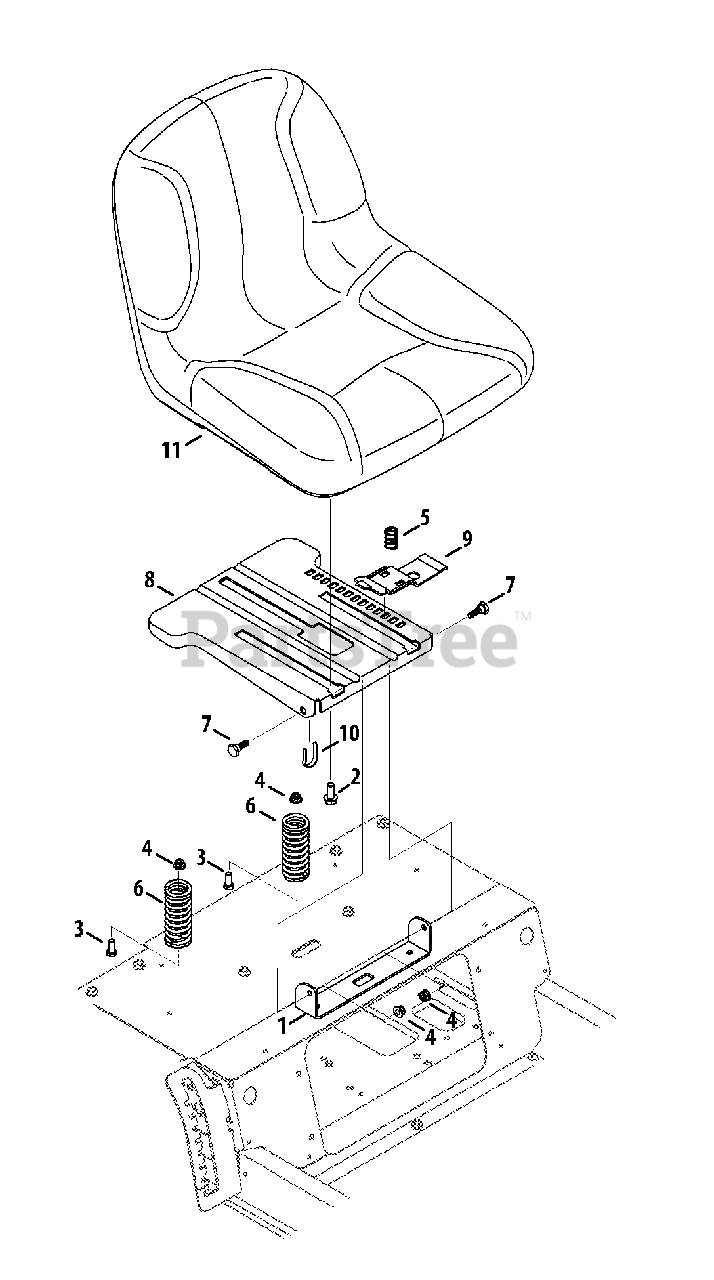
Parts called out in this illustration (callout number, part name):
1	Seat Bracket
2	Hex Flange Bolt, 3/8-16 x .875
3	Hex Cap Screw, 5/16-18 x .750
4	Flange Lock Nut, 5/16-18
5	Compression Spring, .68 x 1.065 x .055
6	Compression Spring, 1.50 x 3.90 x .200
7	Shoulder Screw, 5/16-18 x .437 x .268
8	Seat Mount Bracket
9	Seat Adjustment Lever
11	Seat
